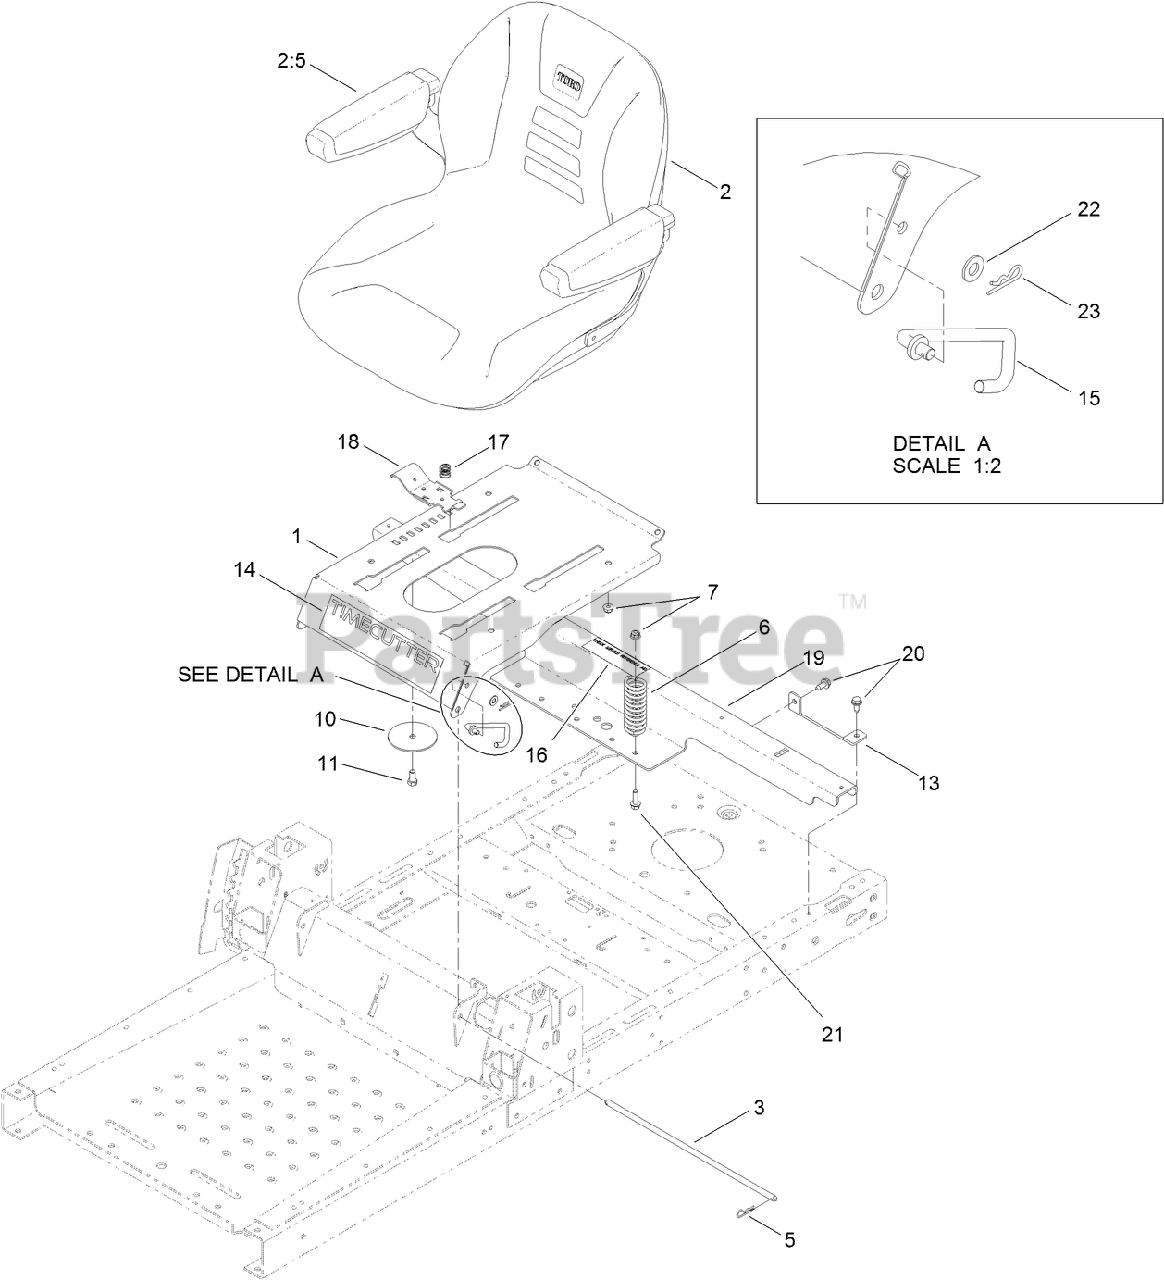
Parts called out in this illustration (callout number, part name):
1	PAN-SEAT
2	18 INCH SEAT ASM
2:5	ARMREST KIT
3	ROD-STOP
5	PIN-COTTER
6	SPRING-COMPRESSION
7	NUT-HF, NI
10	WASHER-SEAT
11	SCREW-HH
13	SUPPORT-TANK, REAR
14	DECAL-TIMECUTTER
15	STOP-SEAT
16	DECAL-SERVICE, CE
17	SPRING-COMPRESSION
18	LATCH-SEAT
19	SUPPORT-POD
20	SCREW-HWHTF
21	SCREW-HHF
22	WASHER-PLAIN
